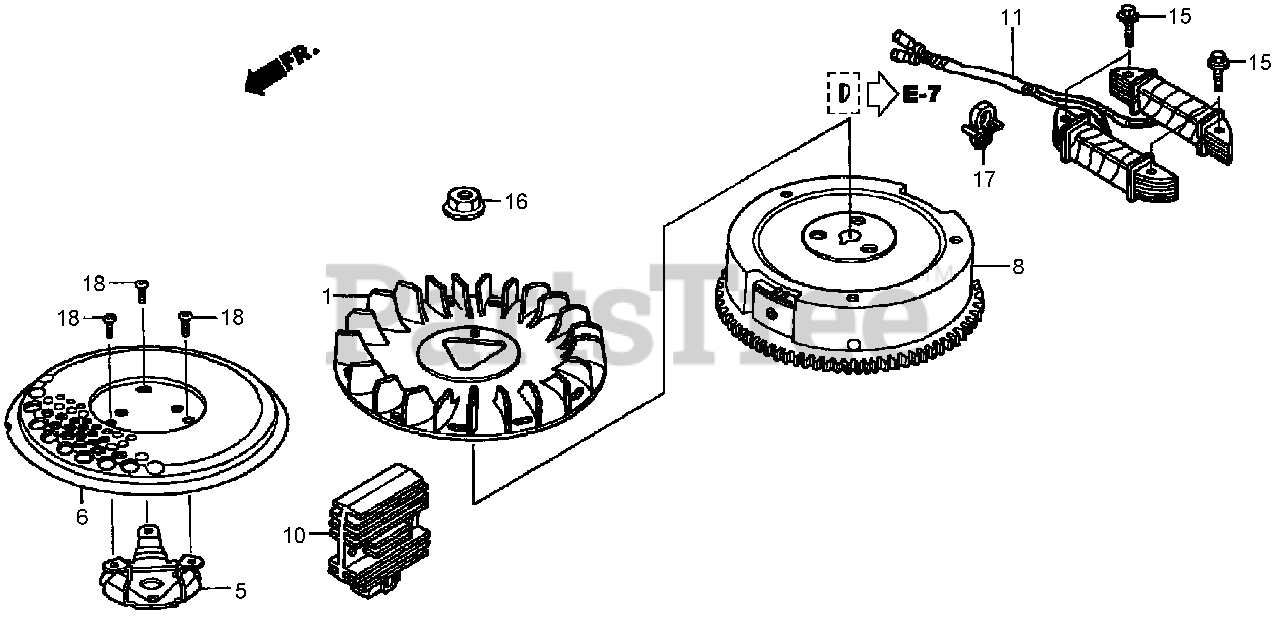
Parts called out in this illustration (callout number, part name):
1	FAN-COOLING
5	HOLDER-GRID, SCREEN
6	GRID-SCREEN
8	FLYWHEEL (SEL-4 POLE)
10	REGULATOR RECTIFIER ASM
11	CHARGE COIL ASM (10A)
15	BOLT-FLANGE (6X32)
16	NUT (16MM)
17	CLIP-HARNESS, WIRE
18	SCREW-PAN (5X8)
